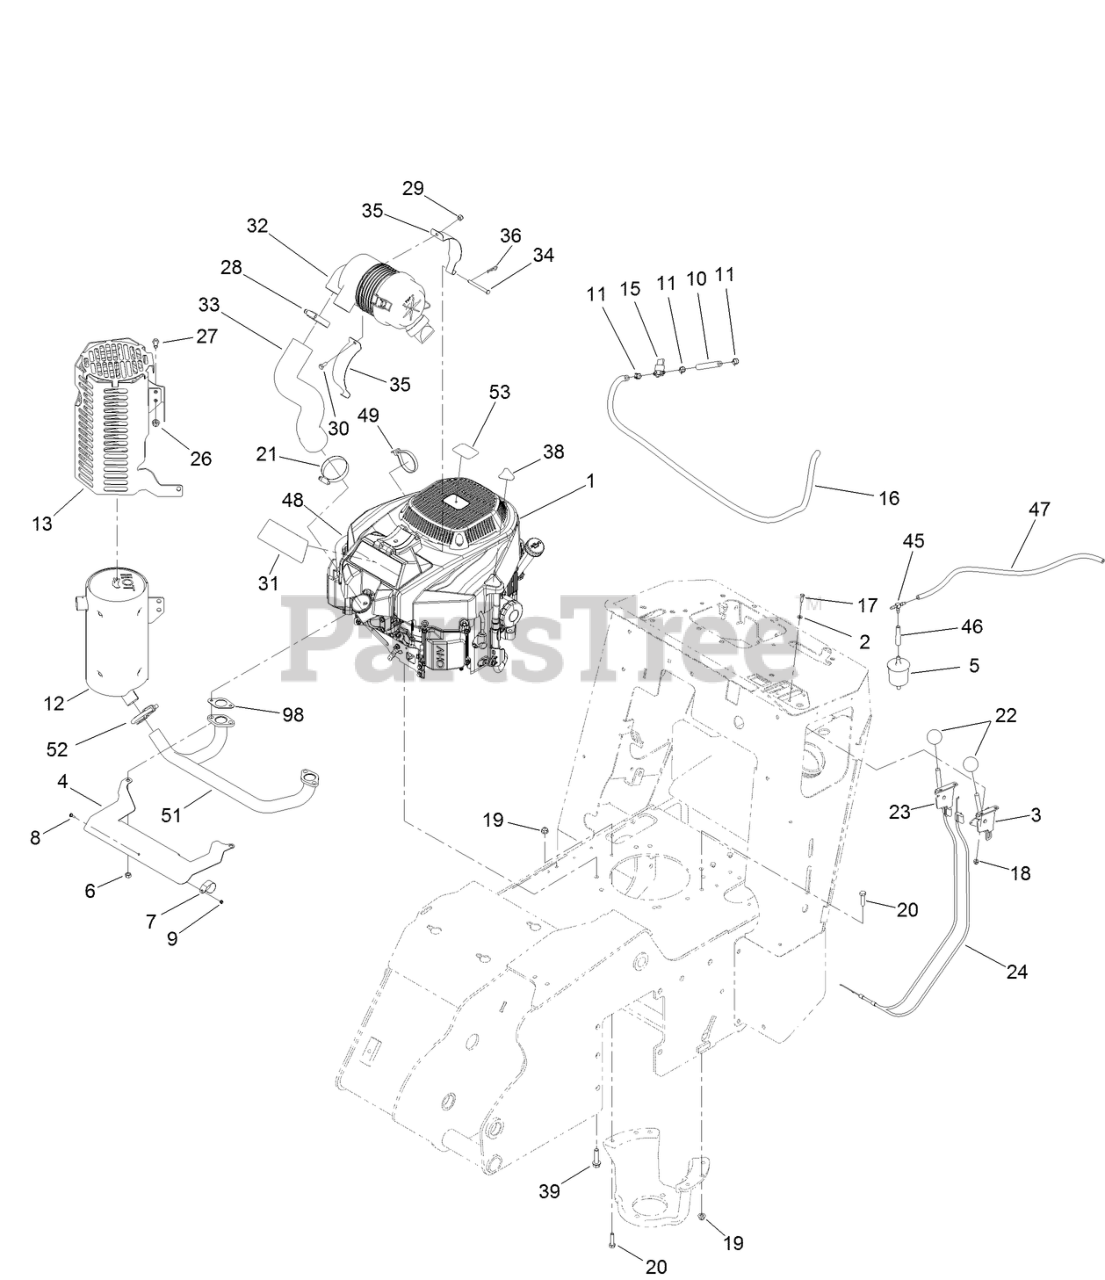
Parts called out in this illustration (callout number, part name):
1	ENGINE
2	WASHER-FLAT
3	LEVER-CONTROL
4	PLATE-SHIELD, HEAT
5	FILTER-FUEL
8	SCREW-PAN
9	NUT-HEX
10	HOSE-FUEL
11	CLAMP-HOSE
12	MUFFLER
13	GUARD-MUFFLER
15	VALVE-FUEL
16	HOSE-FUEL
18	NUT-HF
19	NUT-HF
20	SCREW-HH
21	CLAMP-HOSE
23	LEVER-CONTROL
24	CABLE-CONTROL
26	NUT-FLANGE
27	SCREW-HH
28	CLAMP-HOSE
29	NUT-HEX
30	SCREW-HH
32	AIR CLEANER ASM
33	HOSE-INTAKE
34	PIN-CLEVIS
35	STRAP-CANISTER, AIR
36	PIN-COTTER
38	DECAL-DRAIN, OIL
39	SCREW-HWH
45	FITTING-TEE
46	HOSE-FUEL, MOLDED
47	HOSE-FUEL
48	SLEEVE-THERMAL
49	TIE-CABLE
51	MANIFOLD
52	CLAMP-MUFFLER
98	GASKET-EXHAUST
